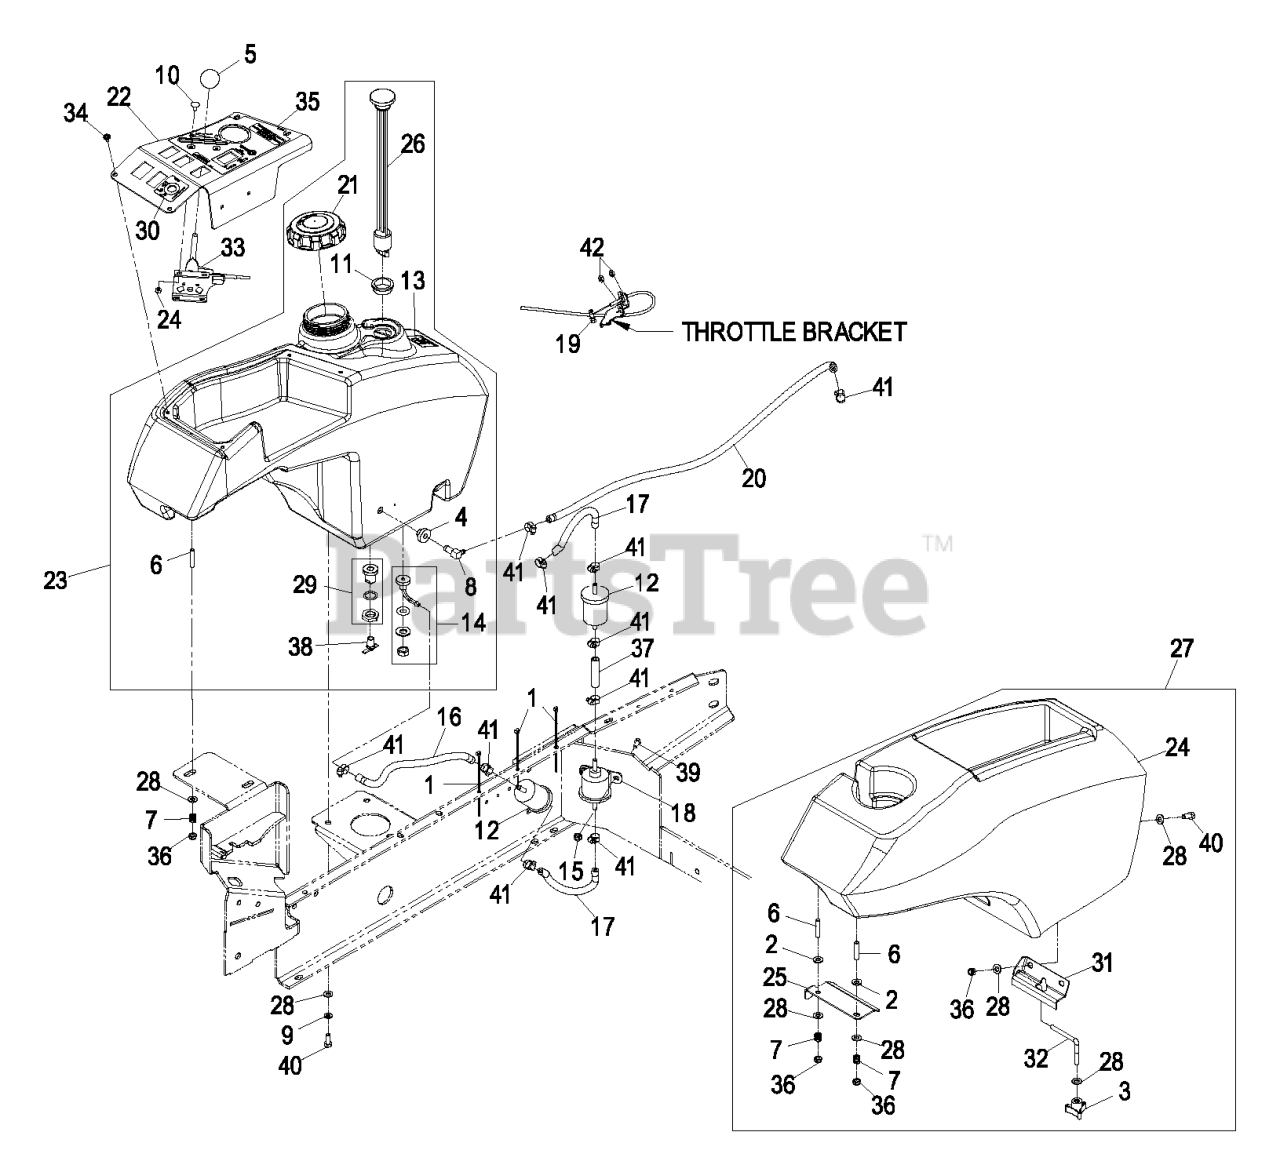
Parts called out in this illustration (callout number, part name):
1	TIE-CABLE
2	WASHER-SPRING
3	KNOB-3 PRONG
5	KNOB-BALL
6	STUD
7	SPRING-TANK, FUEL
8	ELBOW-90 DEG
9	WASHER-LOCK
10	BOLT-CARR
11	CONTACT ORDER SERVICES
12	FILTER-FUEL
13	DECAL-FUEL
14	FITTING-FUEL, BULKHEAD
16	HOSE-FUEL
17	HOSE-FUEL
19	SWIVEL-STOP, CABLE
20	HOSE-FUEL
21	CAP-FUEL, DIESEL
22	ASM,FMZ DIESEL CTRL PANEL
24	NUT-LOCK, NI
25	HOOK,FENDER (PLATED)
26	Gauge, Fuel
27	ASM,FENDER FMZ
28	WASHER-PLAIN
29	Asm, Fitting 1/4" Npt
30	DECAL,IGNITION
31	BRACKET,FENDER
32	BOLT,FENDER
33	CABLE,THROTTLE
34	SCREW-PPH
35	DECAL,CONSOLE FMZ DIESEL
36	NUT-LOCK, NI
37	HOSE-FUEL
38	DRAINCOCK
39	SCREW-HH
40	SCREW-HH
41	CLAMP-WORM
42	NUT-JAM
